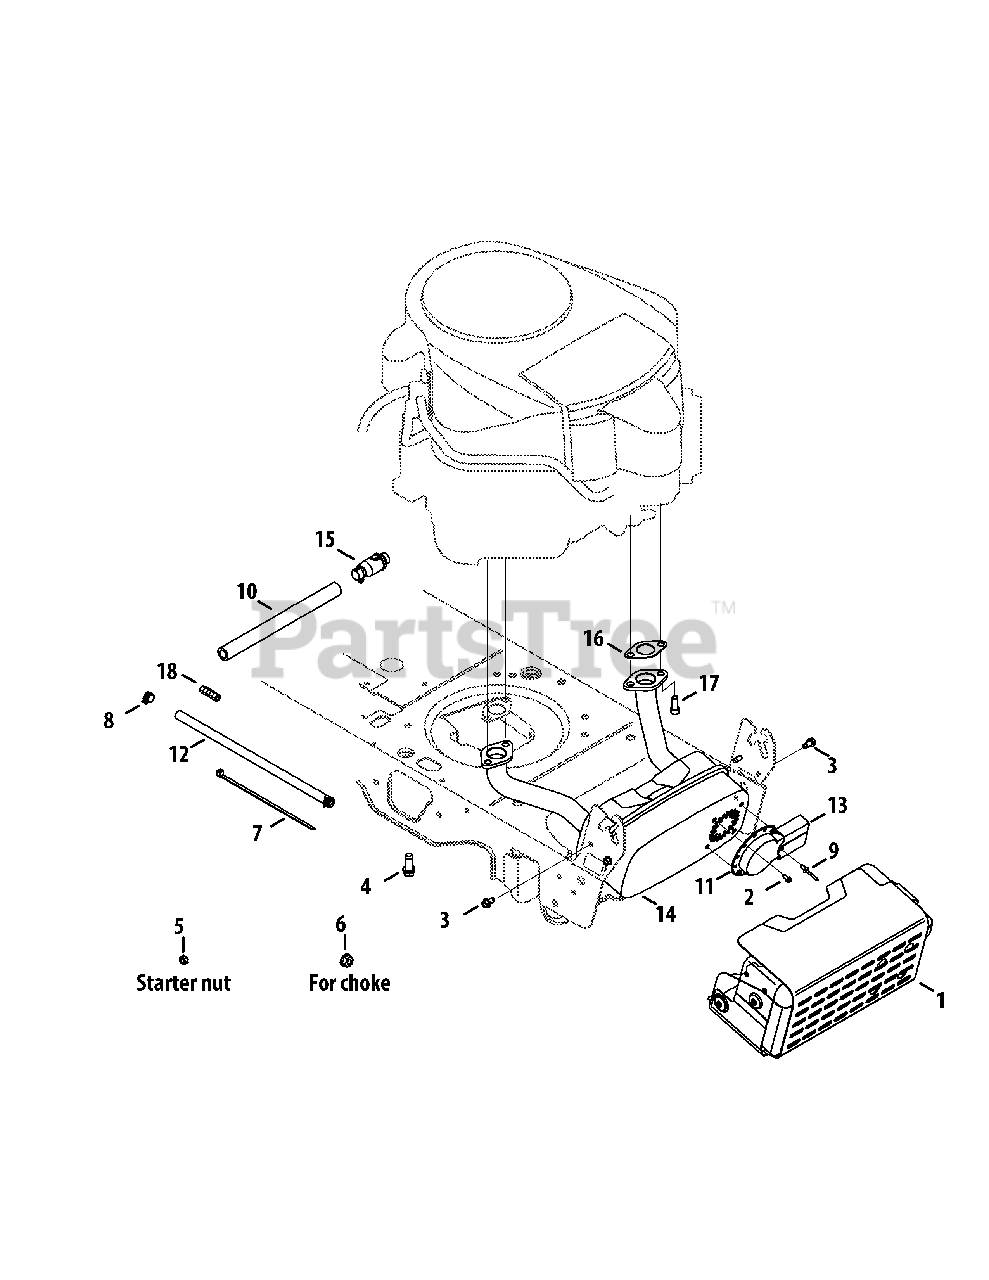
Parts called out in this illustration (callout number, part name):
1	Shield Ass’y, Muffler
2	Screw, Ab, #8-18, 0.500,
3	Screw, Self-tapping, 1/4-20, 0.500,
4	Screw, Self-tapping, 3/8-16, 1.0
4	Screw, Self-tapping, 3/8-16, 1.25
5	Nut, Sems, 1/4-20
6	Nut, Flange Lock, 3/8-16 Kaw.
7	Cable, Tie, 3/16 x .05 x 7.4
8	Clamp, Hose, .490 Dia.
9	Rivet, Pop, .188 Dia x .300
10	Hose, Extension, Oil Drain
11	Deflector, Muffler Koh.
12	Hose, Fuel, Low Permeation, 1/4
13	Deflector, Muffler, Long
14	Muffler
15	Drain, Oil Koh.
16	Gasket, Exhaust, Koh.
17	Screw, Sokt Head, 5/16-18, .750 Koh.
